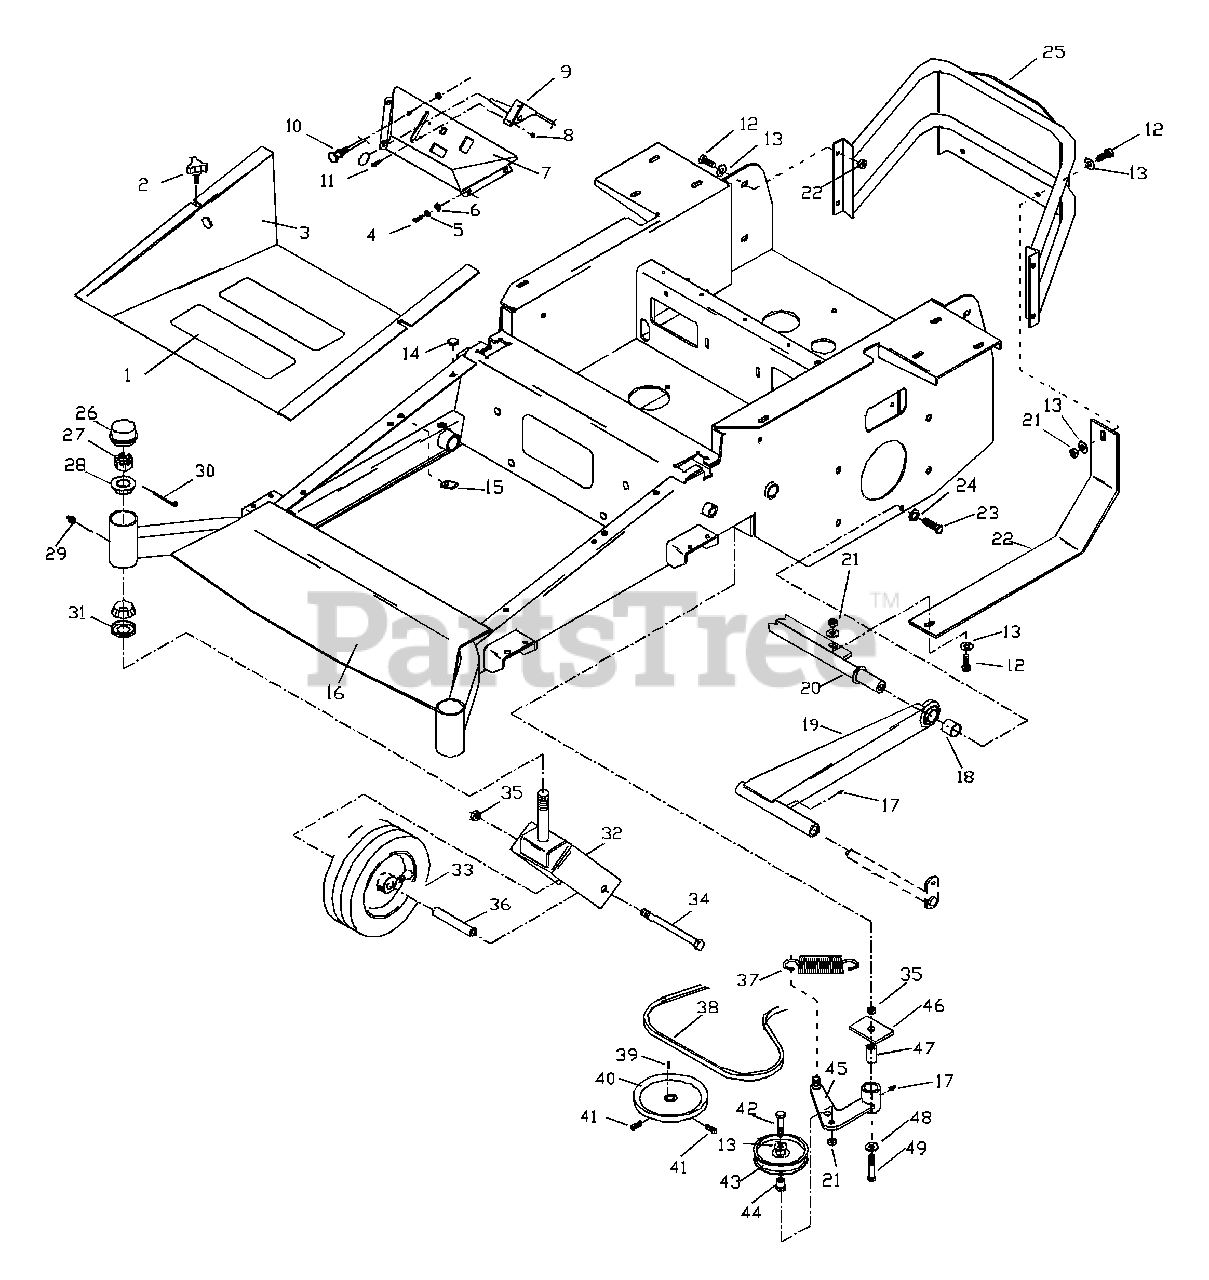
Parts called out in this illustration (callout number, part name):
1	ANTI-SKID PAD
2	KNOB W/ STUD
3	FOOT PLATE
4	HCS 1/4C X 3/4"
5	1/4" LOCK WASHER
6	1/4" FLAT WASHER
7	CONSOLE W/ DECAL
8	# 10-24 NYLOC NUT
9	THROTTLE CABLE
10	CHOKE CABLE
11	#10-24 X 1/2" HCS
12	HCS 3/8C X 1"
13	3/8 FLAT WASHER
16	MAIN FRAME W/DECALS
17	ZERK
18	STRUT SPACER
20	CROSS SHAFT
21	3/8C CENTERLOCK
22	SKID PLATE
23	HCS 7/16C X 1"
24	7/16 LOCK WASHER
25	REAR GUARD
26	CAP, GREASE
27	CASTLE NUT 1" C
28	BEARING W/CUP
29	DRIVE IN ZERK
30	COTTER PIN 1/8 X 2"
32	YOKE, CASTER
33	TIRE & WHEEL ASM.
33	RIM
33	TIRE
33	FLANGE BEARING
33	2.5" ROLLER BEARING
34	HCS 1/2-13 X 7.5" GD. 5
35	1/2C NYLOC NUT
36	SPACER, CASTER
38	PUMP BELT
39	5MM X 25MM KEY SQ.
41	5/16C X 5/8 SET SCREW
42	HCS 3/8C X 1.75
43	IDLER PULLEY
44	IDLER FLANGE BUSHING
45	IDLER ARM
46	SUPPORT PLATE
47	PIVOT BUSHING
48	1/2 FLAT WASHER
49	HCS 1/2C X 3.25 GD. 5
